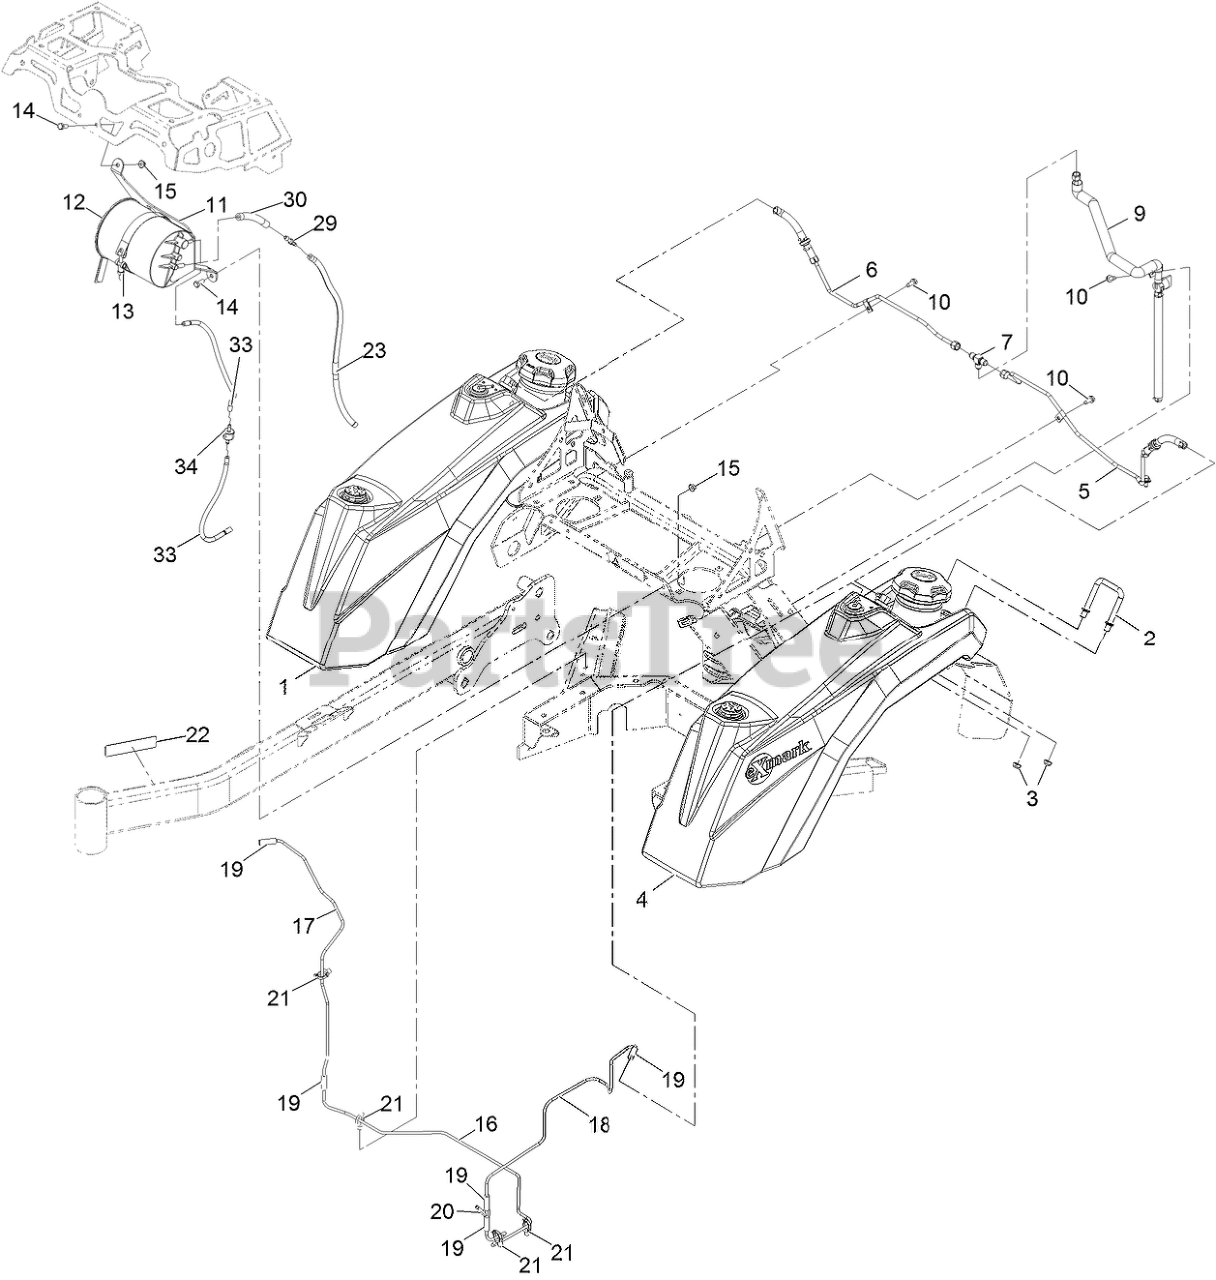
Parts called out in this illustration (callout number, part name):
1	ASM, Rt Fuel Tank
2	Clamp, Tank
4	ASM, Lt Fuel Tank
5	ASM, Left Fuel Line
6	ASM, Right Fuel Line
7	Fitting, 2603-4-4-4
9	ASM, Koh Fuel Line
10	SCREW-HWH
11	Bracket, Carbon Canister
12	CANISTER-CARBON, 1200CC
13	CLAMP, T-BOLT
14	Screw-HH
16	Line, Vent, Main
17	Line, Vent, Right
18	Line, Vent, Left
19	HOSE-FUEL
20	Fitting, 3/16" Y
21	CLIP-TIE
22	DECAL-ARRESTOR, SPARK
23	Hose, Vent
29	FITTING-STRAIGHT
30	HOSE-FUEL
33	HOSE-VENT, FORMED
34	VALVE-CHECK, VACUUM
